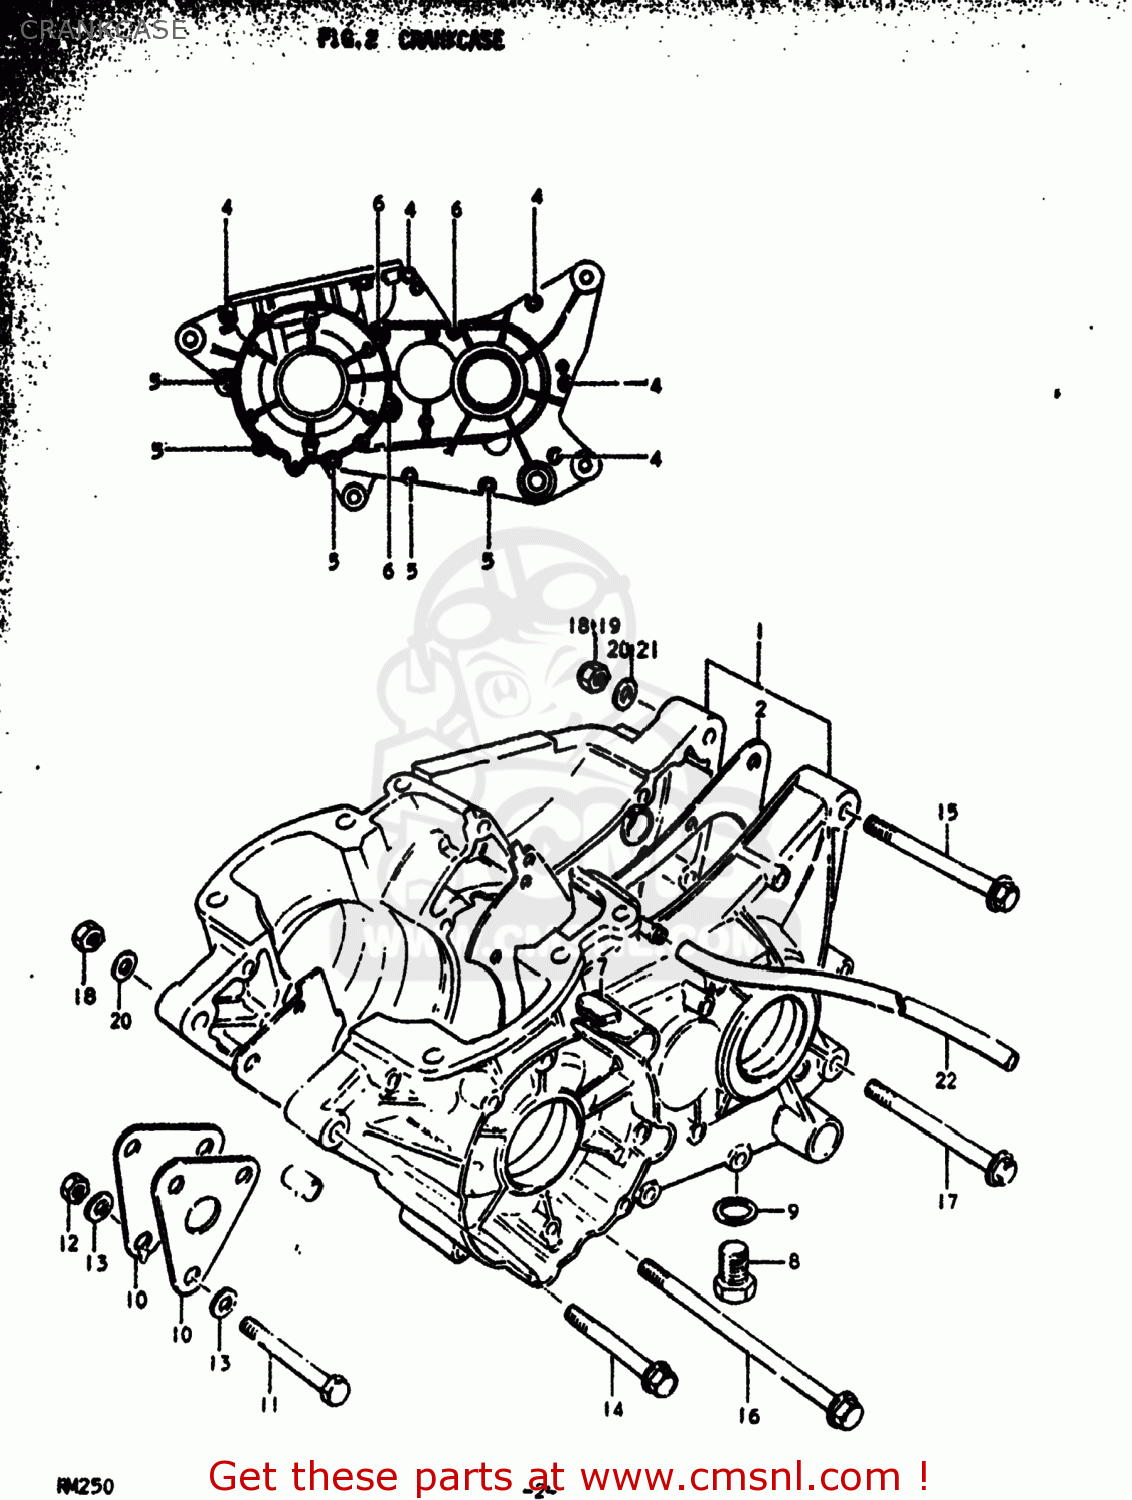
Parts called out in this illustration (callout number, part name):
1	CRANKCASE SET
2	GASKET,CRANKCASE (MCA)
3	PIN
4	SCREW (6X45)
5	SCREW
6	SCREW 6X70
7	PLUG
8	PLUG
9	GASKET(14X19.2X2) (NAS)
10	PLATE,ENGINE MOUNTING
11	BOLT
12	NUT
13	WASHER
14	BOLT
15	BOLT
16	BOLT
17	BOLT(8X80)
18	NUT
19	NUT
20	WASHER
21	WASHER
22	HOSE
